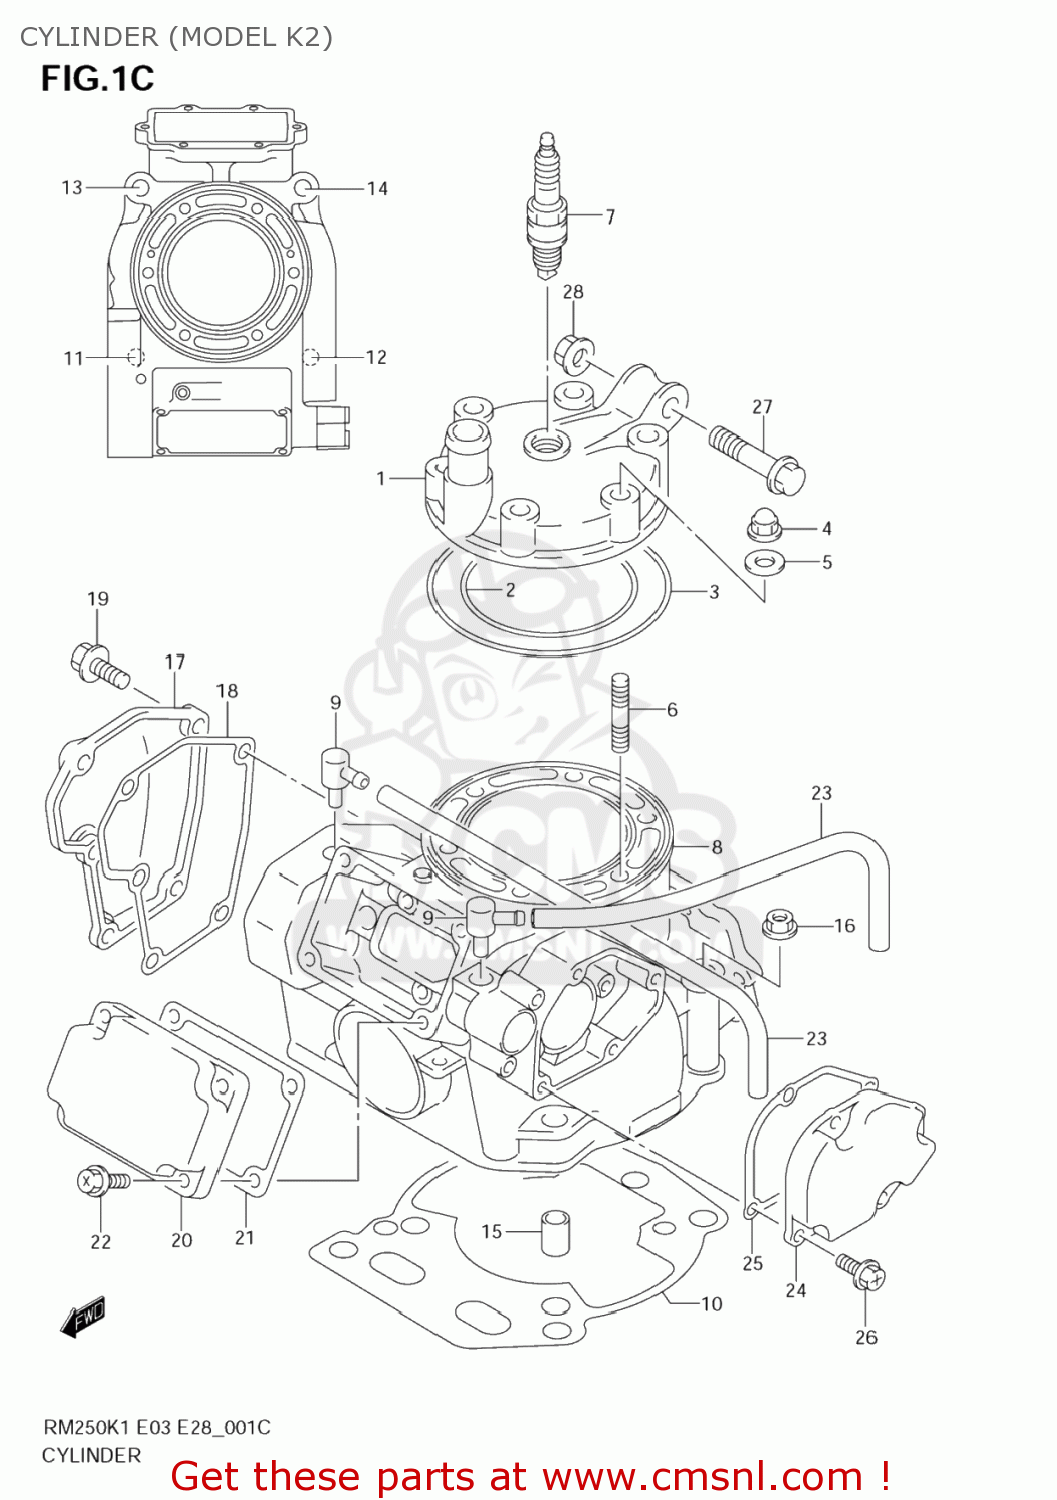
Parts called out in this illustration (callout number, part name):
1	HEAD,CYLINDER
2	O RING,CYLINDER HEAD NO.1
3	O RING,CYLINDER HEAD NO.2
4	NUT
5	GASKET(8.5X17X2.3) (NAS)
6	BOLT,STUD
7	PLUG,SPARK(BR8EG)
8	CYLINDER SET
9	UNION,BREATHER HOSE
10	GASKET,CYLINDER (NAS)
11	STUD 10X30
12	STUD BOLT (L:40)
13	STUD BOLT (L:60)
14	STUD BOLT (L:70)
15	PIN(13X10.4X20)
16	NUT
17	COVER,CYLINDER NO.1
18	GASKET,CYLINDER COVER NO.1 (NAS)
19	BOLT(6X16)
20	COVER,CYLINDER NO.2
21	GASKET,CYL COVER NO.2
22	BOLT
23	HOSE(5X8.2X600)
24	COVER,CYLINDER NO.3
25	GASKET,CYL COVER NO.3 (NAS)
26	BOLT
27	BOLT(10X48)
28	NUT
